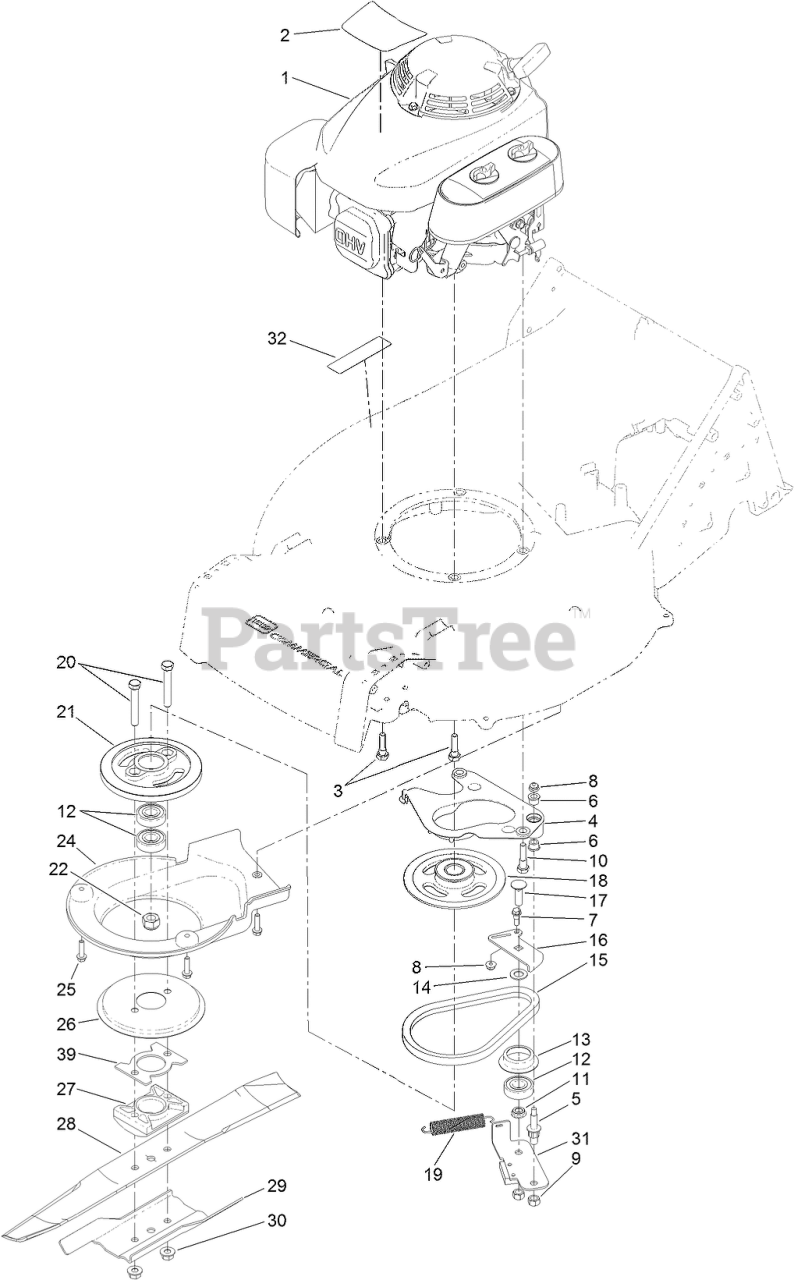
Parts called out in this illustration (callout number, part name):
1	ENGINE-HONDA, GXV160 GAS
2	DECAL-ENGINE, HONDA
3	SCREW-HHSH
4	PLATE-ANCHOR
5	BOLT-SHOULDER
6	BUSHING-FLANGE
7	BOLT-SHOULDER
8	NUT-HF
9	NUT-HEX
10	SCREW-SHOULDER
11	SPACER-BEARING
12	BEARING-BALL
13	RETAINER-BELT
14	WASHER-PLAIN
15	BELT
16	PLATE-GUIDE, BBC
17	BOLT-CARR
18	PULLEY
19	SPRING-TENSION, BRAKE
20	SCREW-HH
21	DRUM
22	NUT-HEX
25	SCREW-HWHTF
26	DISC
27	SUPPORT-BLADE
28	BLADE-RECYCLING
29	ACCELERATOR-BLADE
30	NUT-FLANGE, LOCK
31	PLATE-BRAKE
32	DECAL-ARRESTER, SPARK
39	SPACER-DRIVER, BLADE
